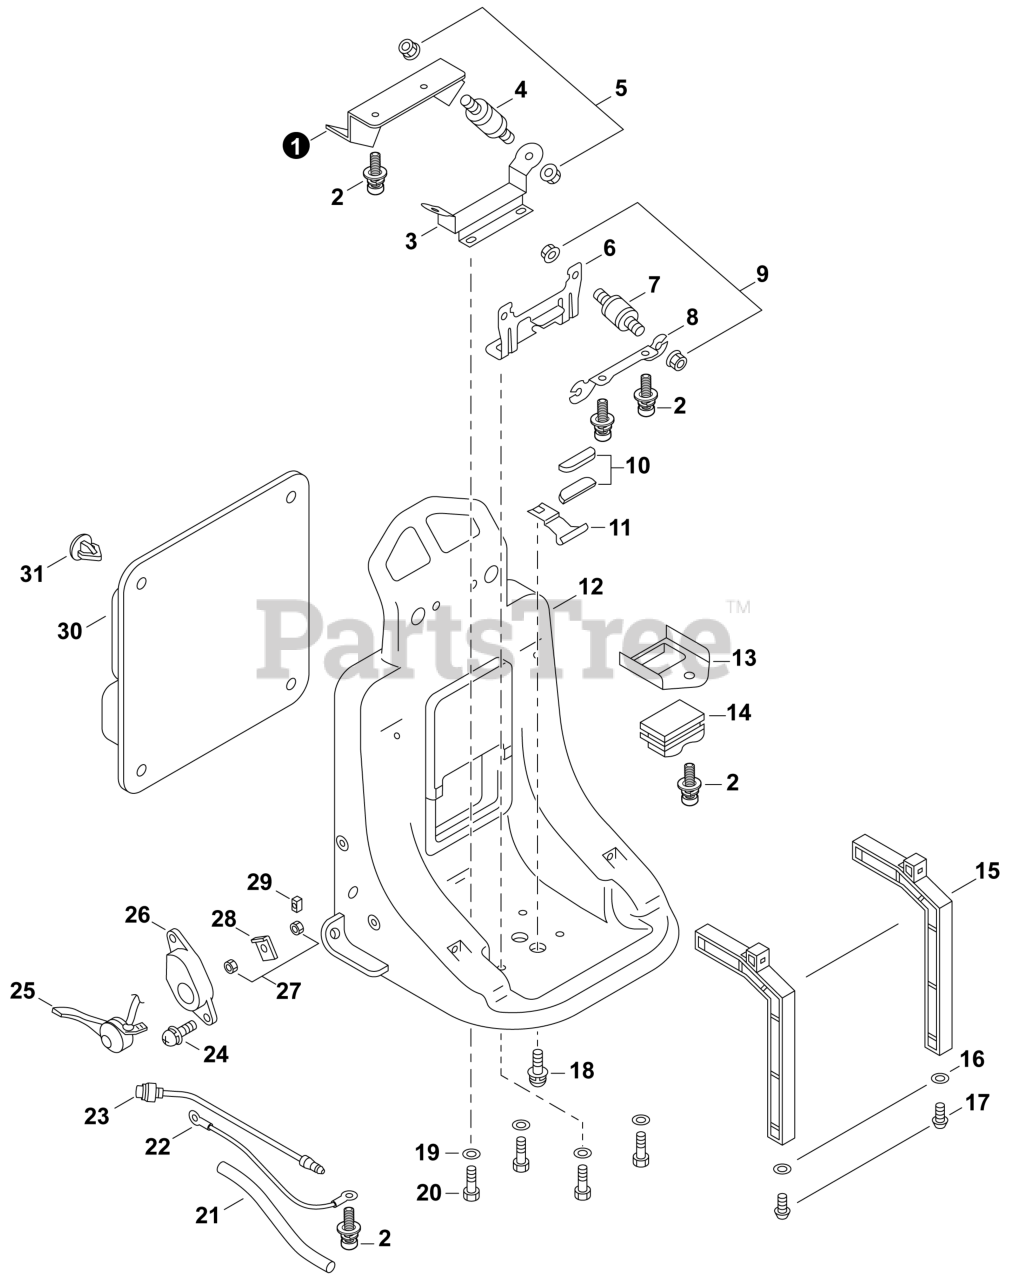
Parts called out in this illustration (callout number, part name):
1	PLATE, ANGLE
2	SCREW 5x12
3	PLATE, ANGLE
5	NUT, FLANGE M6
6	BRACKET, FUEL TANK
8	BRACKET, ENGINE
9	NUT, FLANGE M5
10	CUSHION, FUEL TANK
11	BRACKET, FUEL TANK
12	FRAME, BACKPACK
13	PLATE, ANGLE
15	SUPPORT, CHEMICAL TANK
17	SCREW, TAPPING
18	SCREW 6x15
20	BOLT 6x16
21	PROTECTOR, TUBE
23	SWITCH, STOP
24	SCREW 5x20
25	CONTROL, THROTTLE
26	BRACKET, THROTTLE
28	PLATE, FIXED
30	CUSHION, BACKPACK
